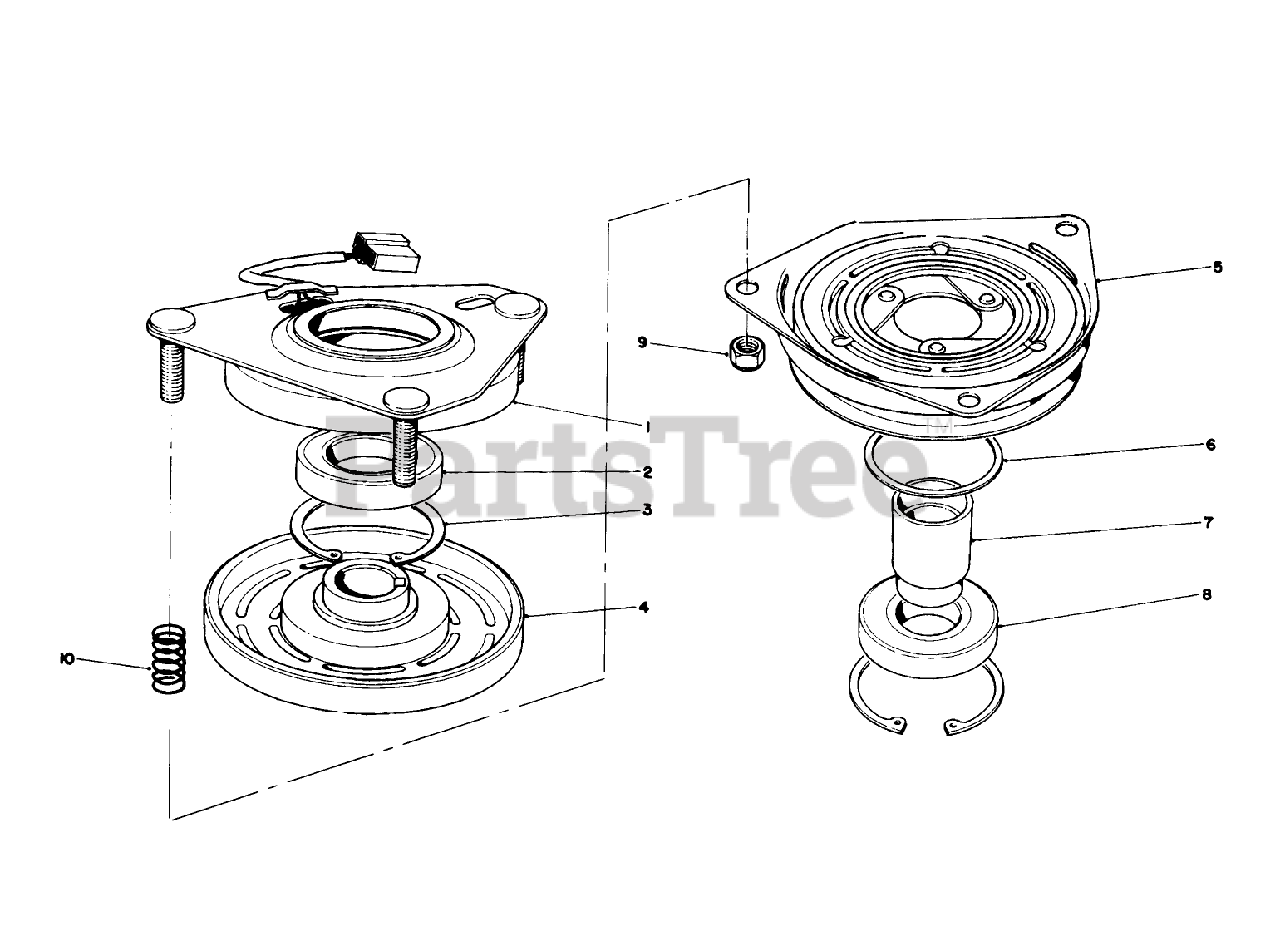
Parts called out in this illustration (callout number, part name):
1	Field Assembly (Incl. Ref. #2 & 3)
2	BEARING-FIELD
3	RING-RETAINING
4	Field Coil, Rotor & Bearing (Incl. Ref. #1)
5	Armature & Pulley Assembly (Incl. Ref. #3, 6, 7 & 8)
6	SPACER-BEARING, PULLEY
7	COLLAR-BEARING
8	BEARING-PULLEY
9	NUT-LOCK
10	SPRING
